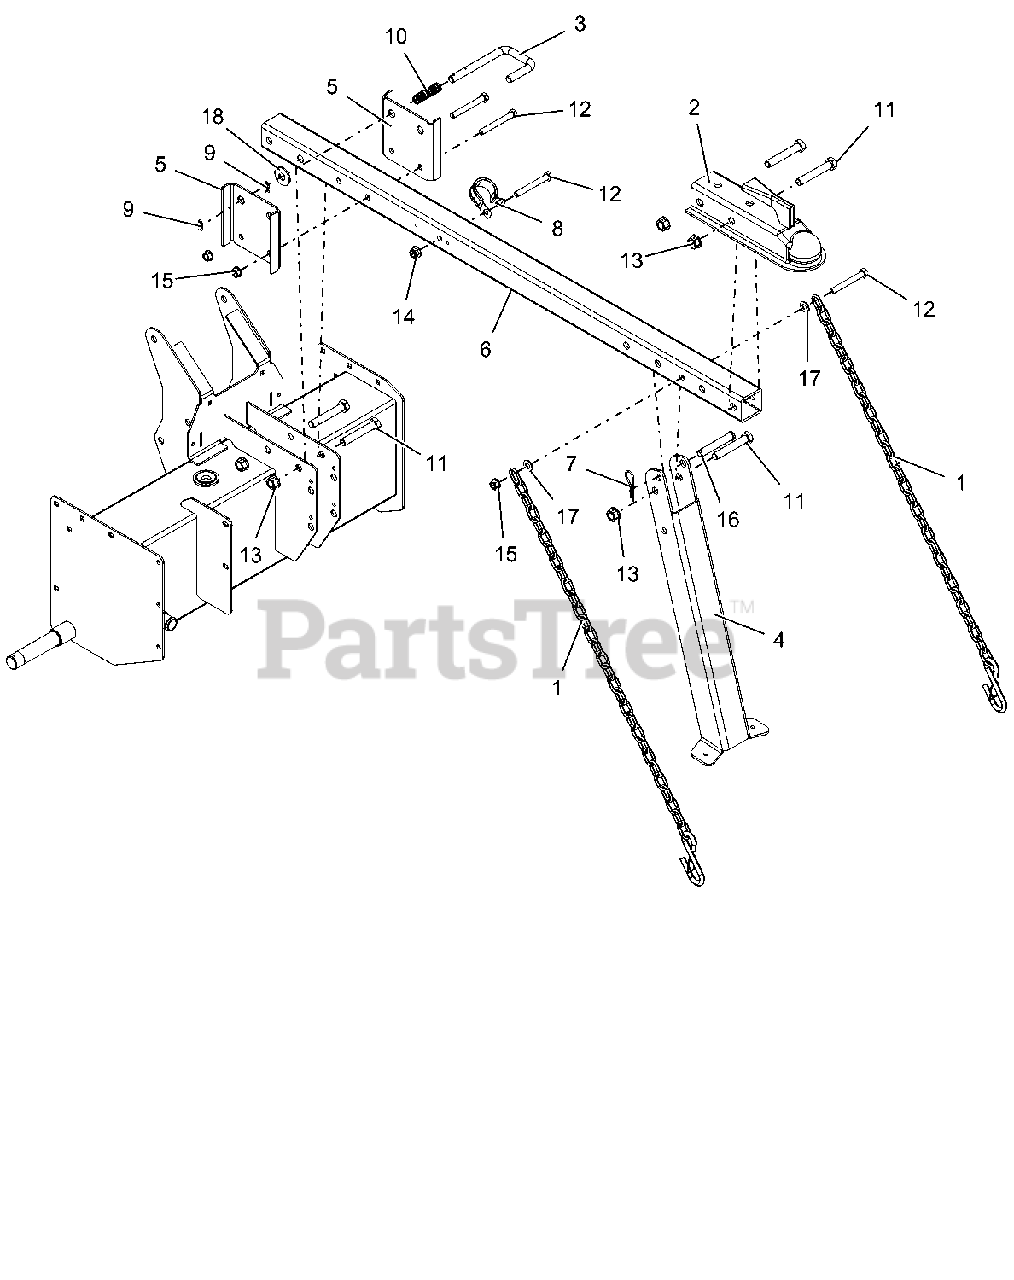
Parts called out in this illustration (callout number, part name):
1	CHAIN, SAFETY 3/16"-30LINK
2	HITCH, BALL-2"
3	LOCK, BEAM
4	LEG SUPPORT-FRONT
5	GUIDE, LOCK DOWN
6	DRAWBAR TUBE W/SAFTY DECAL-22T
7	HAIRPIN, #7 CLIP .094X2.31 YWZ
8	CLAMP, CUSHIONED STEEL 1.25
9	CLIP, SPRING
10	SPRG, COMP .058X.65X2.13 WLD15
11	@BLT-HEX .50-13X3.00 GR5 YWZC
12	@BLT-HEX .38-16X3.00 GR5 YWZC
13	NUT-LK-CTR-FLG .50-13 YWZC
14	@NUT-LK-NYL-FLG .38-16 YWZC
15	@NUT-LK-TOP-FLG .38-16 YWZC
16	PIN, CLEVIS .50 X 3.00 YWZC
17	@WSHR-FL-STL.406X.812X.065 YWZ
18	@WSHR-FL-STL.563X1.38X.109YWZC
